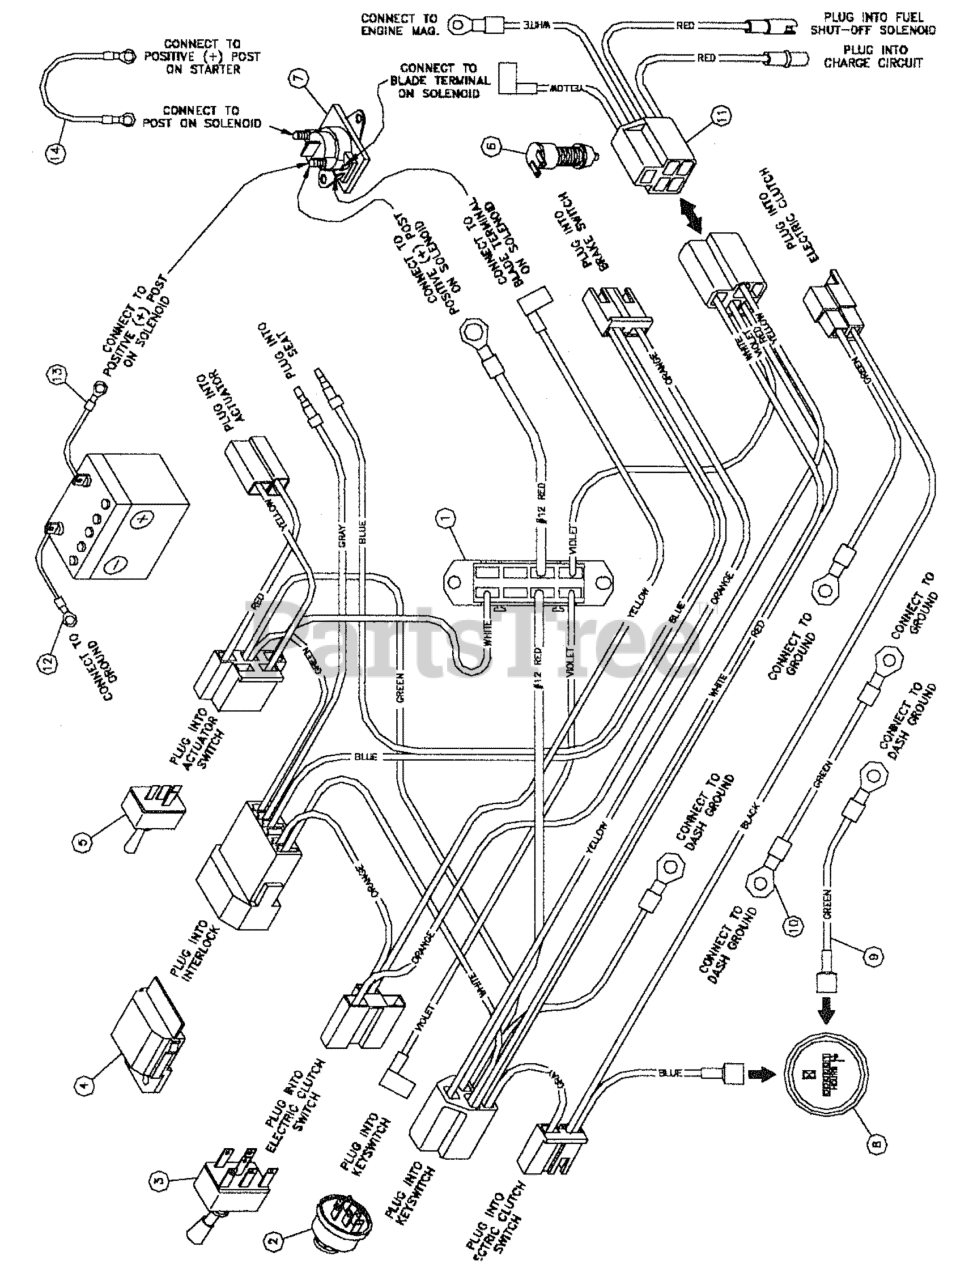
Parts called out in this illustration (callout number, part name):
1	Rider Wire Harness
2	SWITCH, IGNITION, 6 POST
3	Switch, Electric Clutch
4	Interlock, 1601
5	Switch, Electric Actuator
6	Switch, Plunger N. O.
7	Solenoid, Starter
8	Hour Meter
9	Hour Meter Ground Wire
10	Dash Ground Wire
11	Briggs Adapter Harness
12	BATTERY CABLE, NEG, 22, 1/4-5/16
13	Positive (+) Battery Cable
14	Starter Cable
